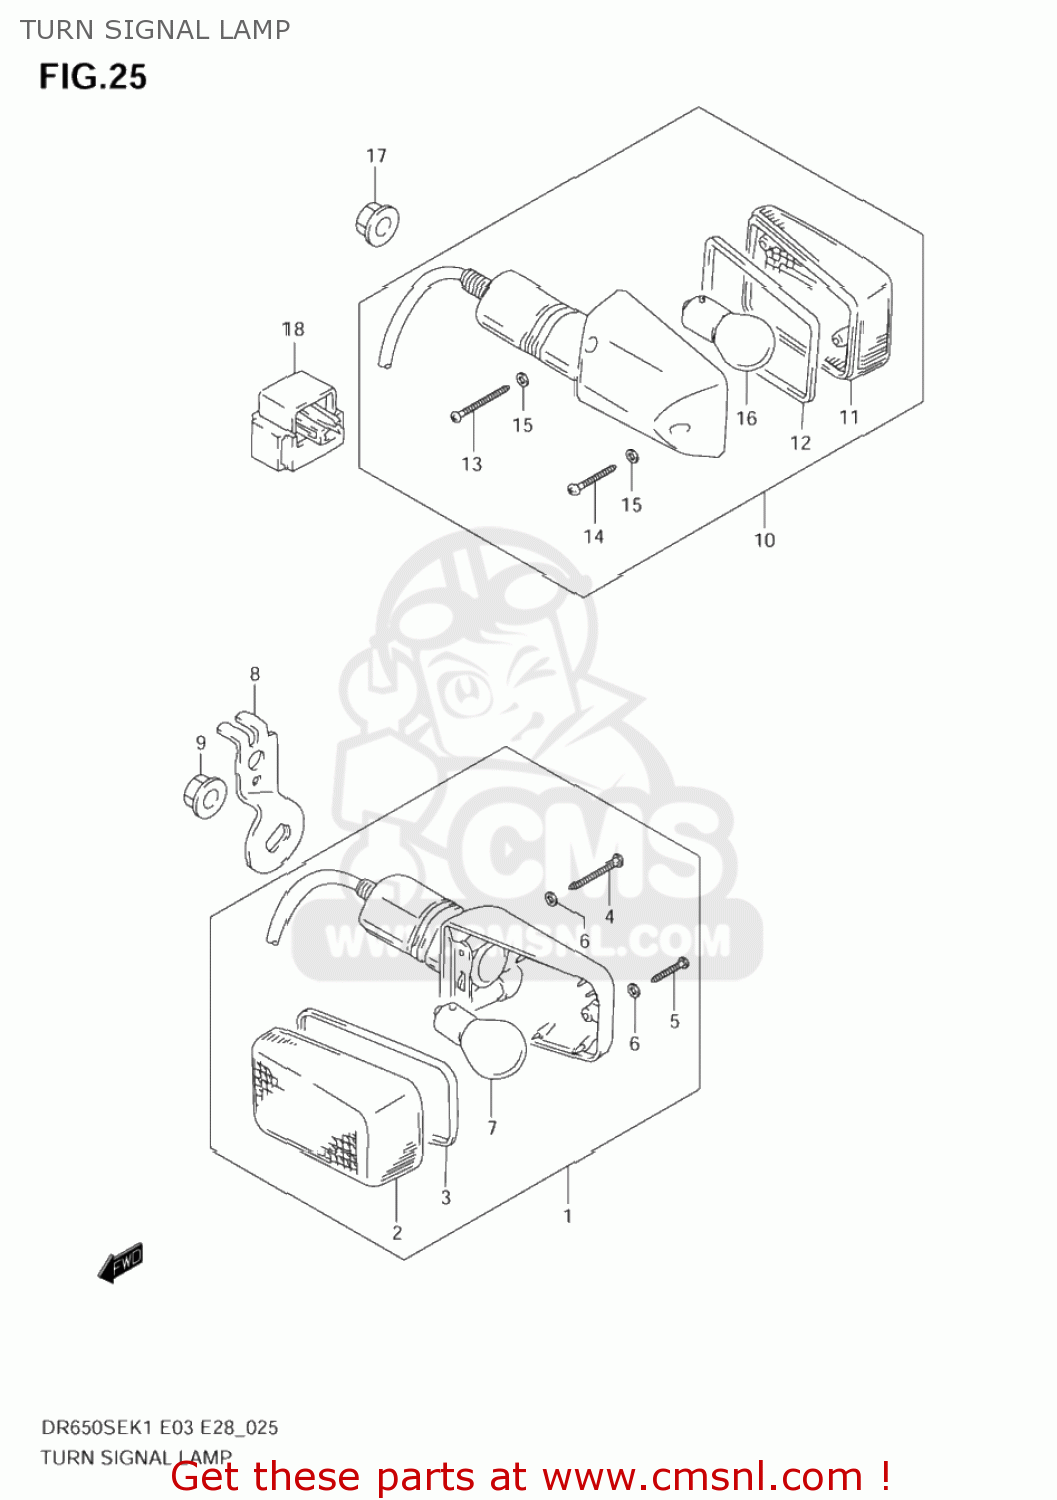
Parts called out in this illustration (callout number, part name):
1	LAMP ASSY,FR TURN SIGNAL
2	LENS
3	GASKET (NAS)
4	SCREW(3X30)
5	SCREW
6	GASKET (NAS)
7	BULB(12V21W)
8	BRACKET,FR TURNSIGNAL,R
9	NUT
10	LAMP ASSY,RR TURNSIGNAL,R
11	LENS
12	GASKET (NAS)
13	SCREW(3X30)
14	SCREW
15	GASKET (NAS)
16	BULB(12V21W)
17	NUT
18	RELAY ASSY
